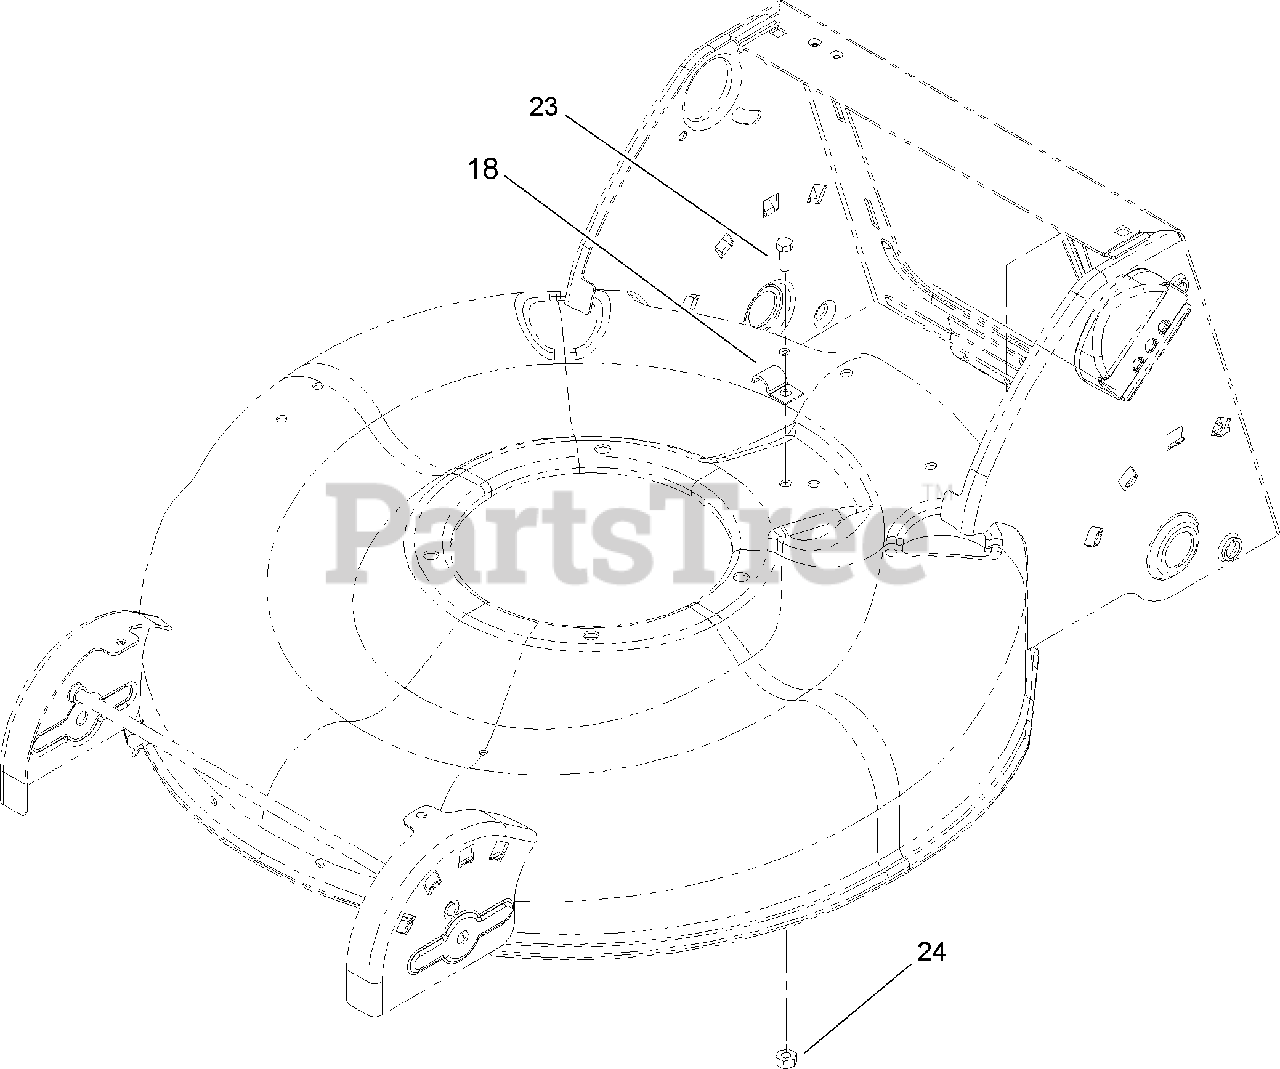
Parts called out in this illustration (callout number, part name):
18	CLIP-HALF
23	SCREW-HH
24	NUT-LOCK, NI
